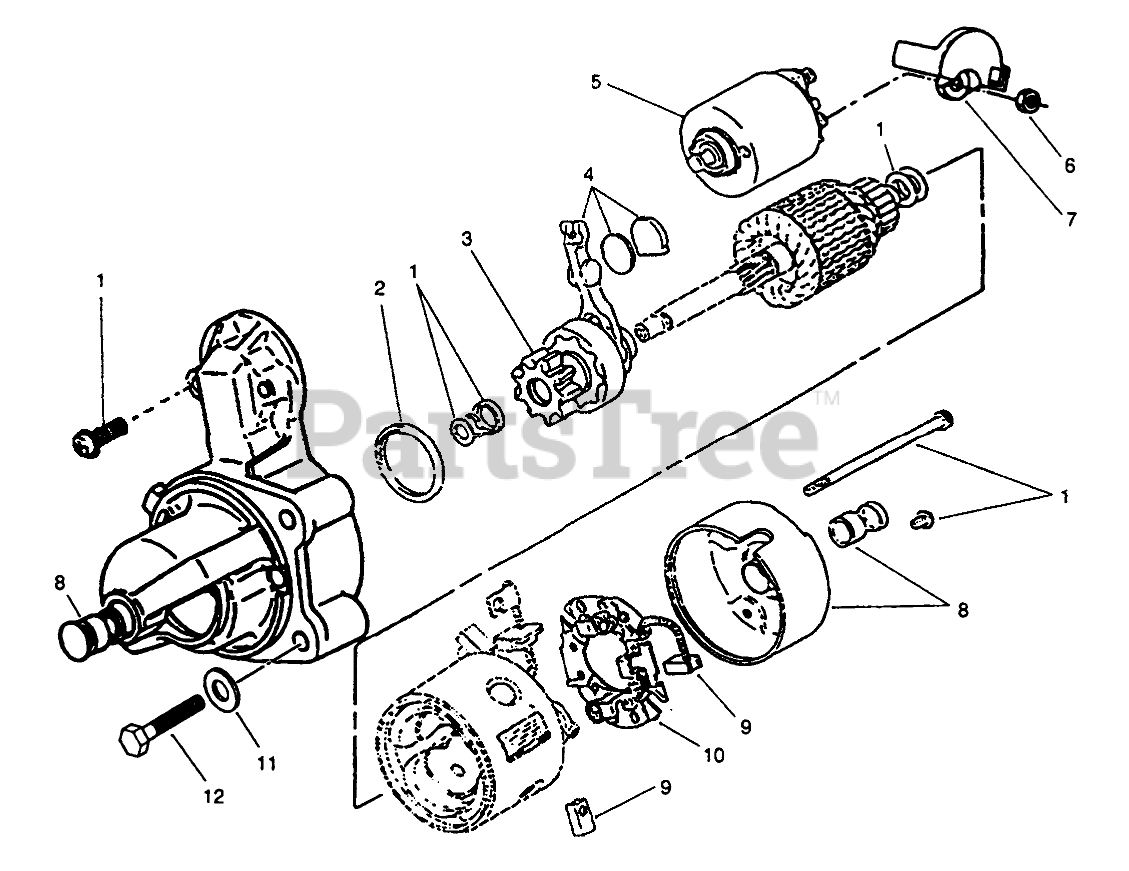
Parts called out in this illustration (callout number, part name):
1	Kit-Hardware, Starter (Incl. Solenoid Screws, Brush Holder Screws, Thru Bolts, Shims, Pinion Stop Collar, & Pinion Retaining Rings)
2	DUST-SEAL KIT
3	CLUTCH STARTER ASSEMBLY
4	LEVER
5	STARTER SOLENOID KIT
6	Nut-Hex.
7	Cap-Starter Solenoid
8	Kit-Bushing, Starter (Incl. Rear Cap, Front & Rear Bushings)
9	Kit-Brush, Starter (Incl. Ref. #10)
10	Holder-Brush, Starter
11	WASHER
12	Screw-Hex Hd
13	KIT-MTG BRKT
14	WASHER
